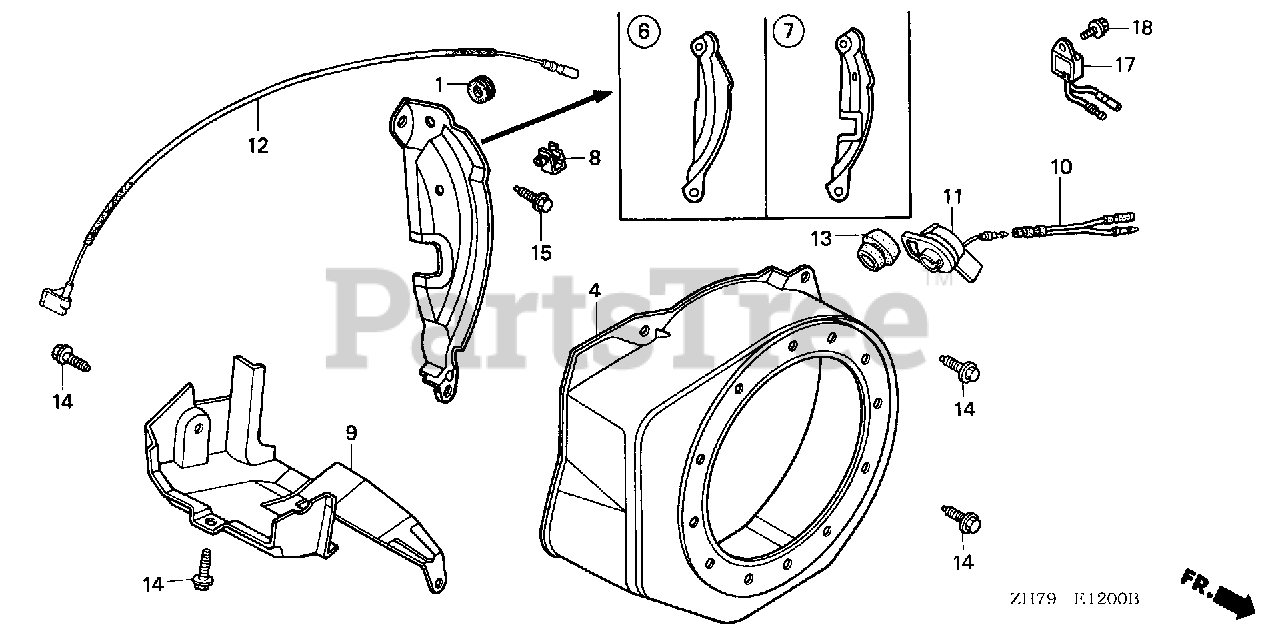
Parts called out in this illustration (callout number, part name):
1	GROMMET, ADJUSTING COVER
4	COVER, FAN *R8* (BRIGHT RED)
6	PLATE, SIDE (STD)
9	SHROUD
11	SWITCH ASSY., ENGINE STOP
12	WIRE, STOP SWITCH (370MM)
14	BOLT, FLANGE (6X12) (CT200)
15	BOLT, FLANGE (6X20) (CT200)
